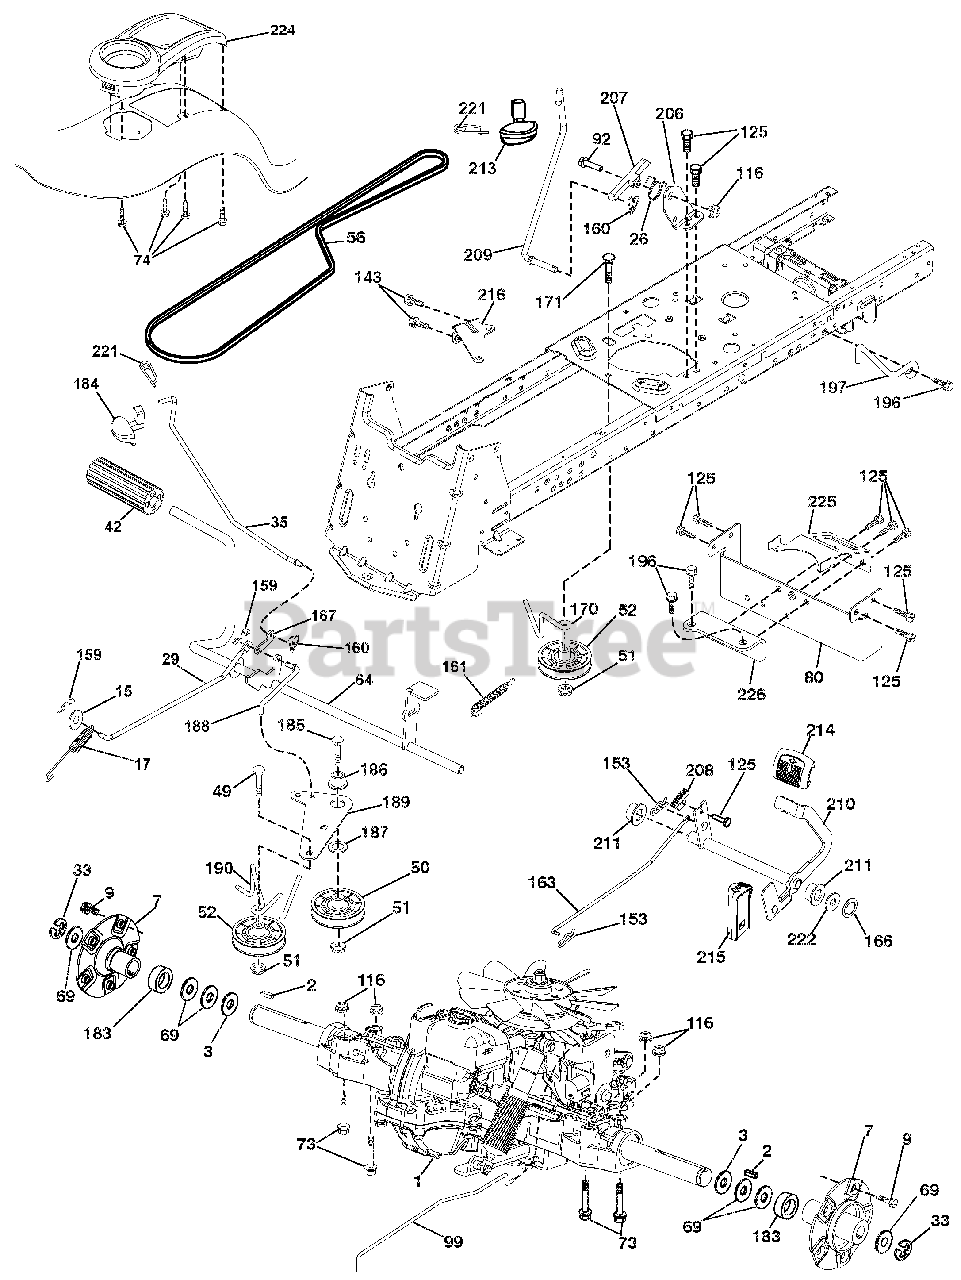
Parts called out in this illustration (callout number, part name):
1	TRANSAXLE
2	KEY 1/4 X 2.5
3	WASHER THRUST AXLE HARDENED
7	HUB ASM. WHEEL
9	BOLT HUB WHEEL
15	WASHER.13/32 X 13/16 X 16 GA.
17	SPRING, BRAKE
26	SPRING.RETURN.CRUISE
29	ROD, BRAKE
35	ROD.BRAKE.PARKING.LT.TEX
42	COVER.PEDAL.BLK.ROUND
49	BOLT.RDHD.3/8-16UNCX1-3/4.GR5
50	IDLER.FLAT.910"OFFSET
51	Nut, Hex, Flangelock 3/8-16
52	IDLER.V-GROOVE.910"OFFSET
56	V-BELT.GROUND DRIVE.90.00
64	SHAFT ASM.PEDAL.BRK.CNTRL.PCH
69	WASHER 1-1/32 X 1-5/8 X 16 GA.
73	BOLT.HEX.FLGHD.5/16-18.GR.5
74	SCREW.HEX.WSH.HI-LO.1/4X1/2UNC
80	STRAP TORQUE
92	Bolt, Hex Head 5/16-18 x 1-1/4
99	ROD BYPASS
116	Nut, Lock Hex Flange 5/16-18 u
125	SCREW.5/16-18X3/4.SMGML.TAP/BL
143	SCREW.THDROL.5/16-18 X 1/2TYTT
153	Retainer Spring
159	PIN.COTTER.1/8 X 3/4.CAD.
160	RETAINER.CLIP(M).DIA.290
161	SPRING.RETURN.CLUTCH.6.75
163	ROD PEDAL CONTROL
166	NUT PUSH .625
167	LATCH.BRAKE.PARKING
170	KEEPER BELT CENTERSPAN
171	BOLT.RD.HD.SQ.NK.3/8-16UNC X 2
183	SPACER AXLE
184	HANDLE.PARKING BRAKE.LTTEX.505
185	BOLT.RDHD.3/8-16UNC X2-3/4 GR5
186	SPACER.RETAINER
187	WASHER.13/32 X 2 X 10 GA.
188	LINK.CLUTCH.GROUND DRIVE
189	BELLCRANK.GROUNDRIVE.NSTG/NSTL
190	KEEPER.BELLCRANK.DRIVE.GROUND
196	SCREW.3/8-16X1.SMGML.TAP/R.BLK
197	BRACKET CLUTCH ANTI-ROTATION
206	BRACKET.MOUNT.LATCH.CRUISE
207	LATCH.CONTROL.CRUISE
208	GEAR SECTOR.CONTROL.CRUISE
209	ROD.CONTROL.CRUISE.LT.ELITE
210	ROCKER ASM. PEDAL CONTROL
211	BEARING.NYLON.BLK..629 ID.
213	HANDLE.CONTROL.CRUISE.ELTE.428
214	HANDLE.CONTROL.CRUISE.ELTE.428
215	PEDAL.REVERSE.TEX.GT.428
216	BRACKET.PULLEY.IDLER.WTEX
221	RETAINER.SPRING.CLIP.HANDLE
222	WASHER.21/32X1-1/4.10GA.N/PLTD
224	CONSOLE TOOLBOX
225	KEEPER BELT TRANS.
226	BRACKET MOUNT TORQUE
